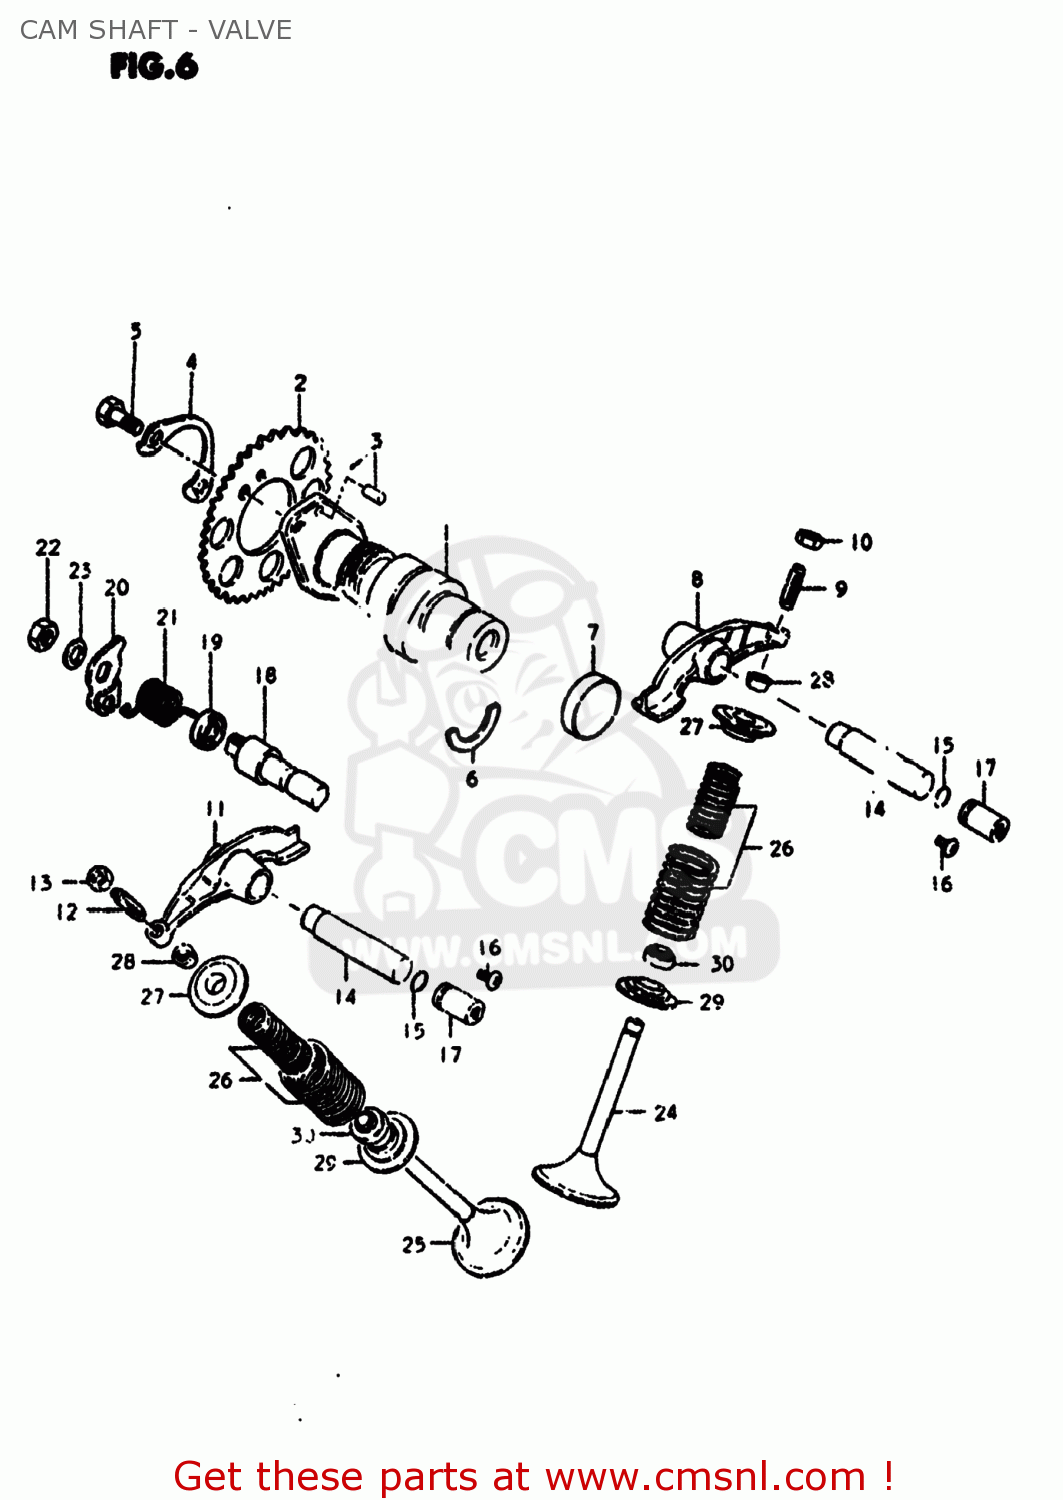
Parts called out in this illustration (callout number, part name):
1	CAMSHAFT
2	SPROCKET,CAMSHAFT
3	PIN
4	WASHER,CAM CHAIN SPROCKET
5	BOLT(6X12.5)
6	C RING
7	PLUG
8	ARM,VALVE ROCKER
9	SCREW,TAPPET ADJUSTING
10	NUT,ADJUSTING SCREW
11	ARM,VALVE ROCKER,EXHAUST
12	SCREW,TAPPET ADJUSTING
13	NUT,ADJUSTING SCREW
14	SHAFT,VALVE ROCKER
15	O-RING
16	SCREW
17	CAP,ROCKER ARM SHAFT
18	SHAFT,DECOMPRESSION
19	OIL SEAL
20	LEVER,DECOMPRESSION SHAFT
21	SPRING
22	NUT 8MM
23	WASHER
24	VALVE,INTAKE
25	VALVE,EXHAUST
26	SHIM,TAPPET
27	RETAINER,VALVE SPRING
28	COTTER VALVE
29	SEAT,VALVE SPRING
30	SEAL,OIL(7X14.4X9)
